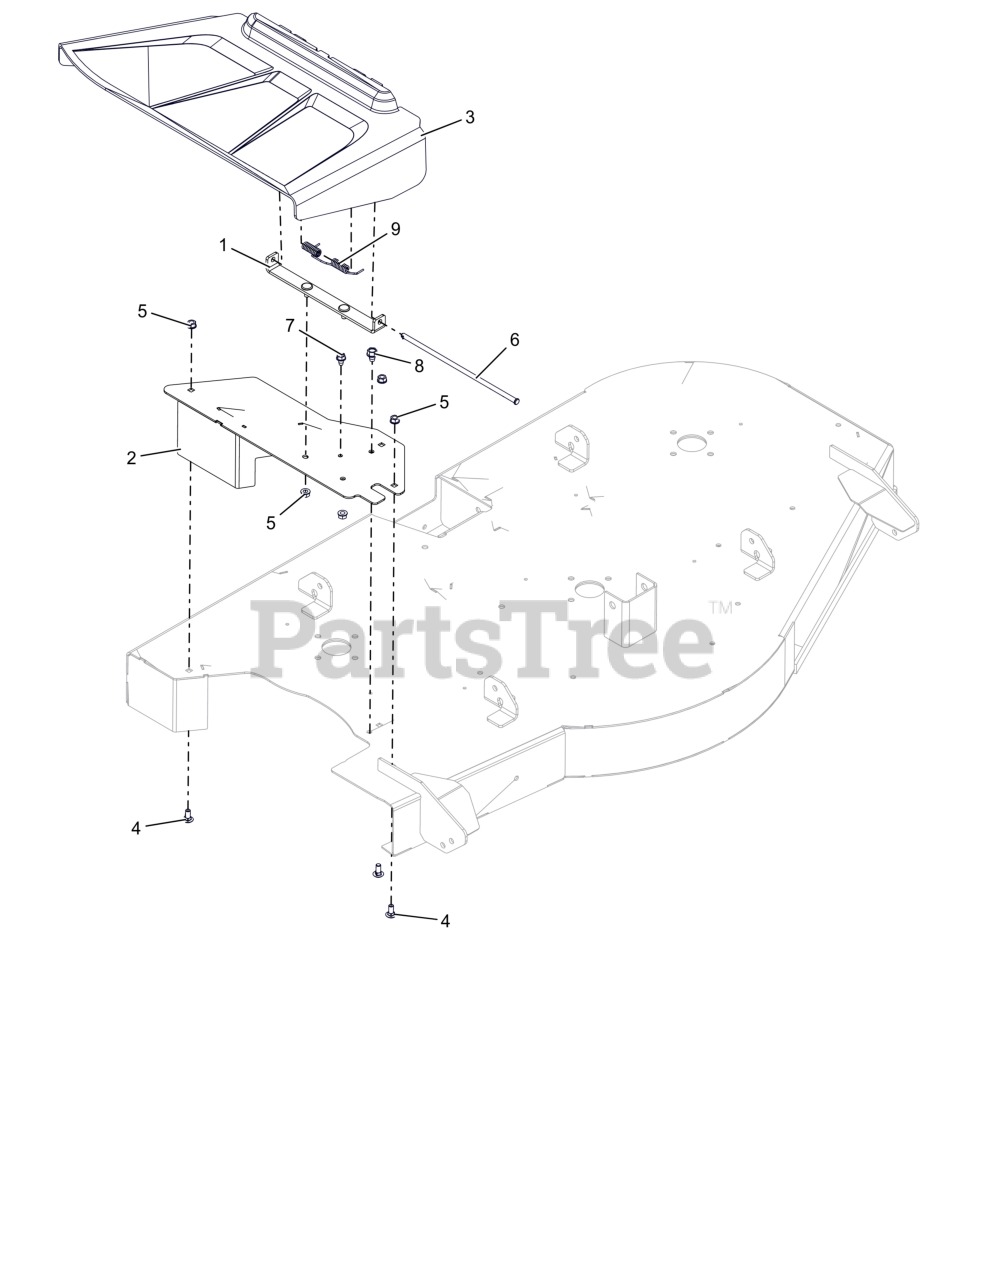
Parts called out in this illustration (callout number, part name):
2	WLDMT, DISCHARGE PLATE (RED)
3	CHUTE, SIDE DISCHARGE
4	BLT,RHSN .31-18X.75 G5 ZCC
5	NUT,LK-CTR-FLG .31-18 GF ZCC
6	PIN, SLIC-.312X10.45
7	SCR,TAP .312-18X.50 HWH TR ZCC
8	SCR,TAP .375-16X.50 HWH TR ZCC
9	SPRING-TORSION
